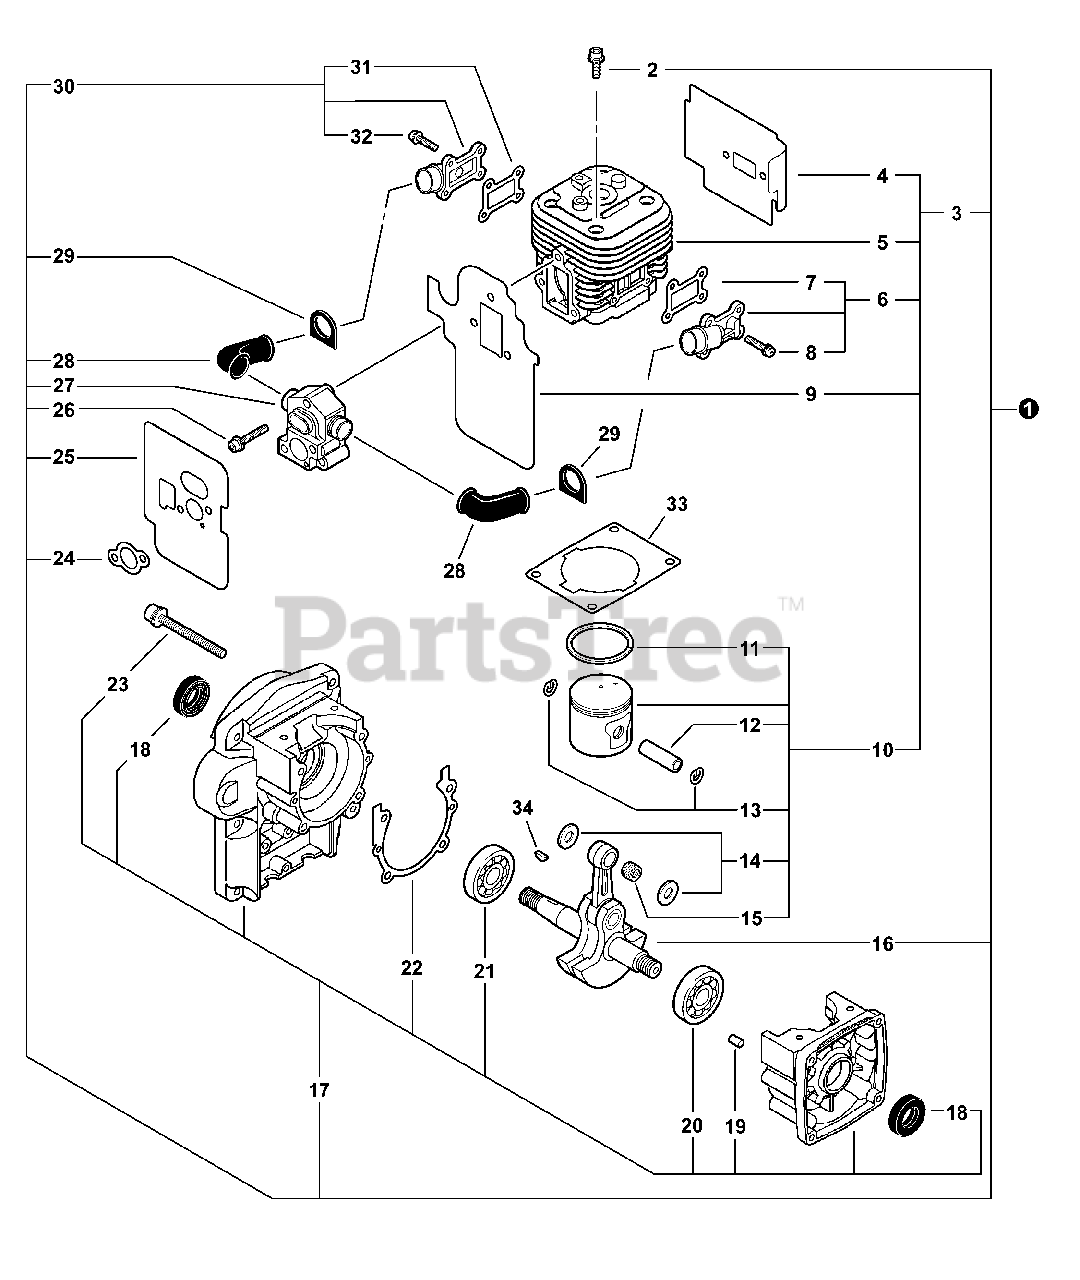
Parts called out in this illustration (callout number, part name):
1	SHORT BLOCK - REPOWER
2	BOLT 5×22
3	CYLINDER/PISTON KIT
4	HEAT SHIELD, EXHAUST
5	CYLINDER
6	REED VALVE KIT (S)
9	GASKET, INTAKE
10	PISTON KIT
16	CRANKSHAFT ASSY
17	CRANKCASE ASSY
18	SEAL, OIL
19	PIN, LOCATING 4×8
20	BEARING, BALL 6202
21	BEARING, BALL 6302 C3
22	GASKET, CRANKCASE
23	BOLT 5×40
24	GASKET, INTAKE
25	GASKET, INTAKE
27	INSULATOR
28	HOSE, AIR
29	GROMMET
30	REED VALVE KIT (M)
31	GASKET, INTAKE
33	GASKET, CYLINDER
34	KEY, WOODRUFF 3×14
